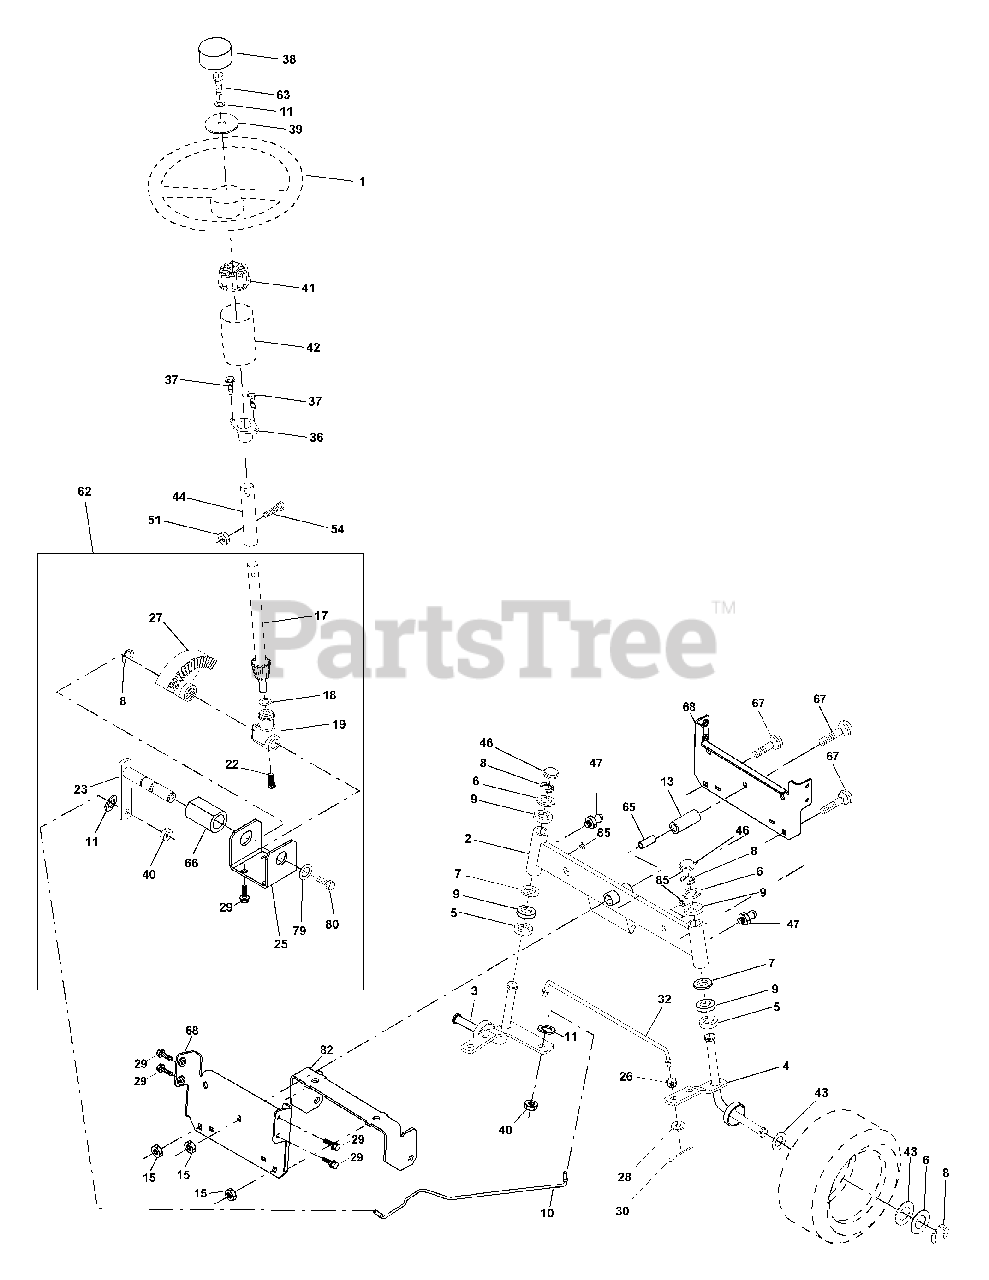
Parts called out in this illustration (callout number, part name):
1	Wheel Steering
2	Axle Asm Stmp Dropped STLT
3	Spindle Asm LH
4	Spindle Asm RH
5	Bearing Race Thrust Harden
6	Washer 25/32 X 1-5/8 X 16 Ga
7	Washer 27/32 X 1-1/4 X 16 Ga
8	Ring Klip #t5304-75
9	Bearing Col Strg Blk
10	Link Drag
11	Washer Lock Hvy Hlcl Spr 3/8
13	Spacer Bearing Axle Front
15	Nut Lock Hex Flange
17	Shaft Asm Strg
18	Washer Thrust 515x 750x 033
19	Support Shaft
22	Screw Hex Wsh Hd Torx
23	Shaft Asm Pittman
25	Bracket Steering
26	Bushing Link Drag
27	Gear Sector
28	Washer 13/32 x 7/8 x 16 Ga.
29	Screw 3/8-16 x 3/4
30	Pin Cotter 1/8 x 3/4 Cad.
32	Rod Tie
36	Bushing Strg
37	Screw
38	Insert Cap Strg Wh Au
39	Washer 13/32 X 2-3/8 X 12 Ga
40	Lock nut
41	Adaptor Wheel Strg
42	Boot Steering Dash
43	Washer 25/32 X 1 1/4 X 16 Ga
44	Extension Steering Shaft LR/LT
46	Cap Spindle Fr Top Blk
47	Fitting Grease
51	Nut Lock Hex w/Ins 5/16-18
54	Bolt Fin Hex 5/16-18 Unc x 1-1/4
62	Kit, Steering Assembly Svc
63	Bolt Fin Hex 3/8-16unc x 1 Gr. 5
65	Spacer Brace Axle
66	Bearing Arm Pittman
67	Bolt, Rdhd Sq 3/8-16 UNC x 2-1/4
68	Axle, Brace
79	Washer 13/32 x 1-1/4 x 12 Ga.
80	Bolt Hex Nylon 3/8-16 x 3/4
82	Bracket Susp Chassis Front
85	Fastener Christmas Tree
